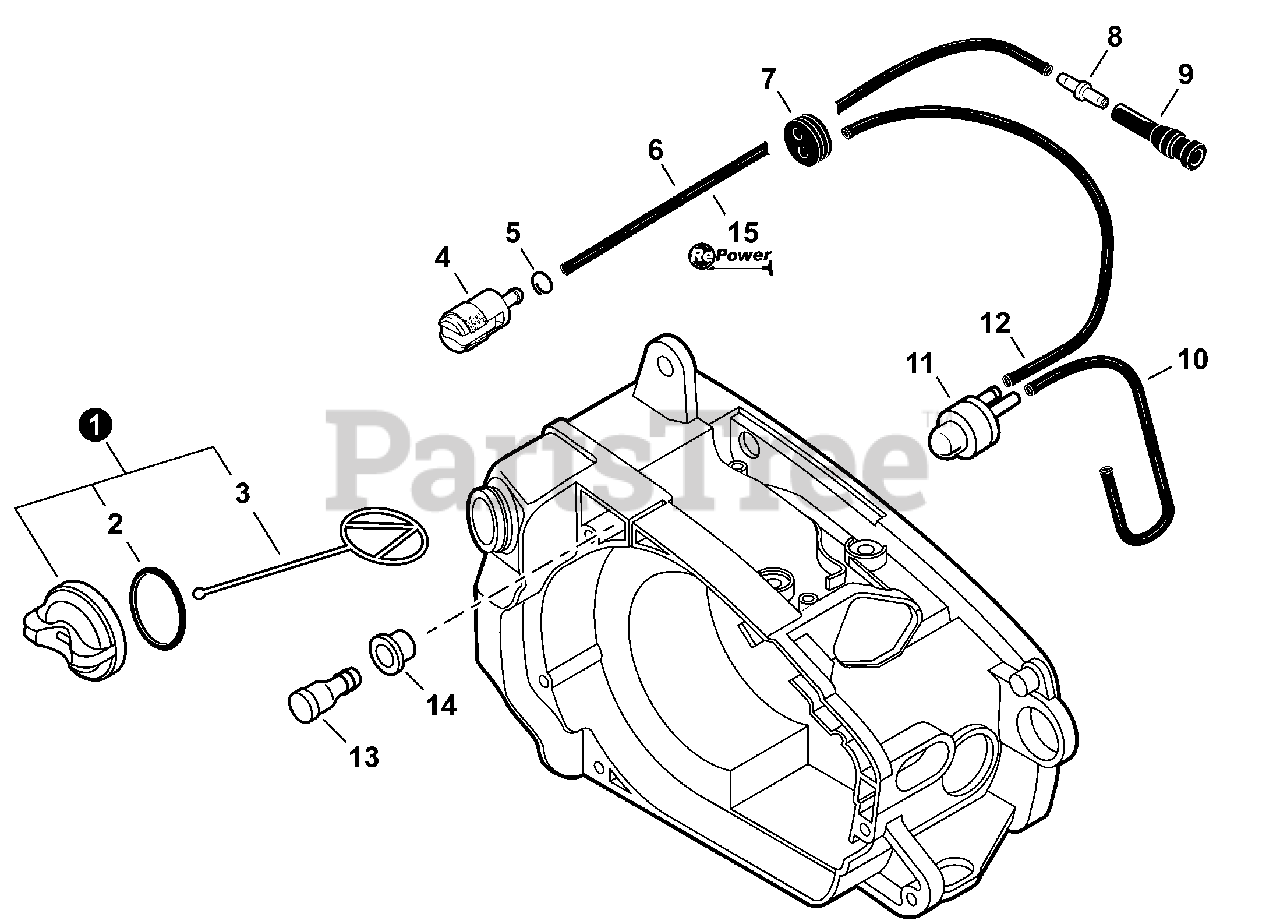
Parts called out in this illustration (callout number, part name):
1	CAP ASSY, FUEL - ORANGE
3	CONNECTOR, CAP L= 60mm
4	FILTER, FUEL
5	CLIP 6MM
6	PIPE, FUEL 3×5×210
7	GROMMET, FUEL
8	CONNECTOR, PIPE
9	PIPE, FUEL
10	PIPE 2.4×5×153
11	BULB, PURGE
12	PIPE 2.4×5×258
13	VENT ASSY
14	GROMMET, FUEL
15	PIPE, BULK - REPOWER 3×5mm BLACK
